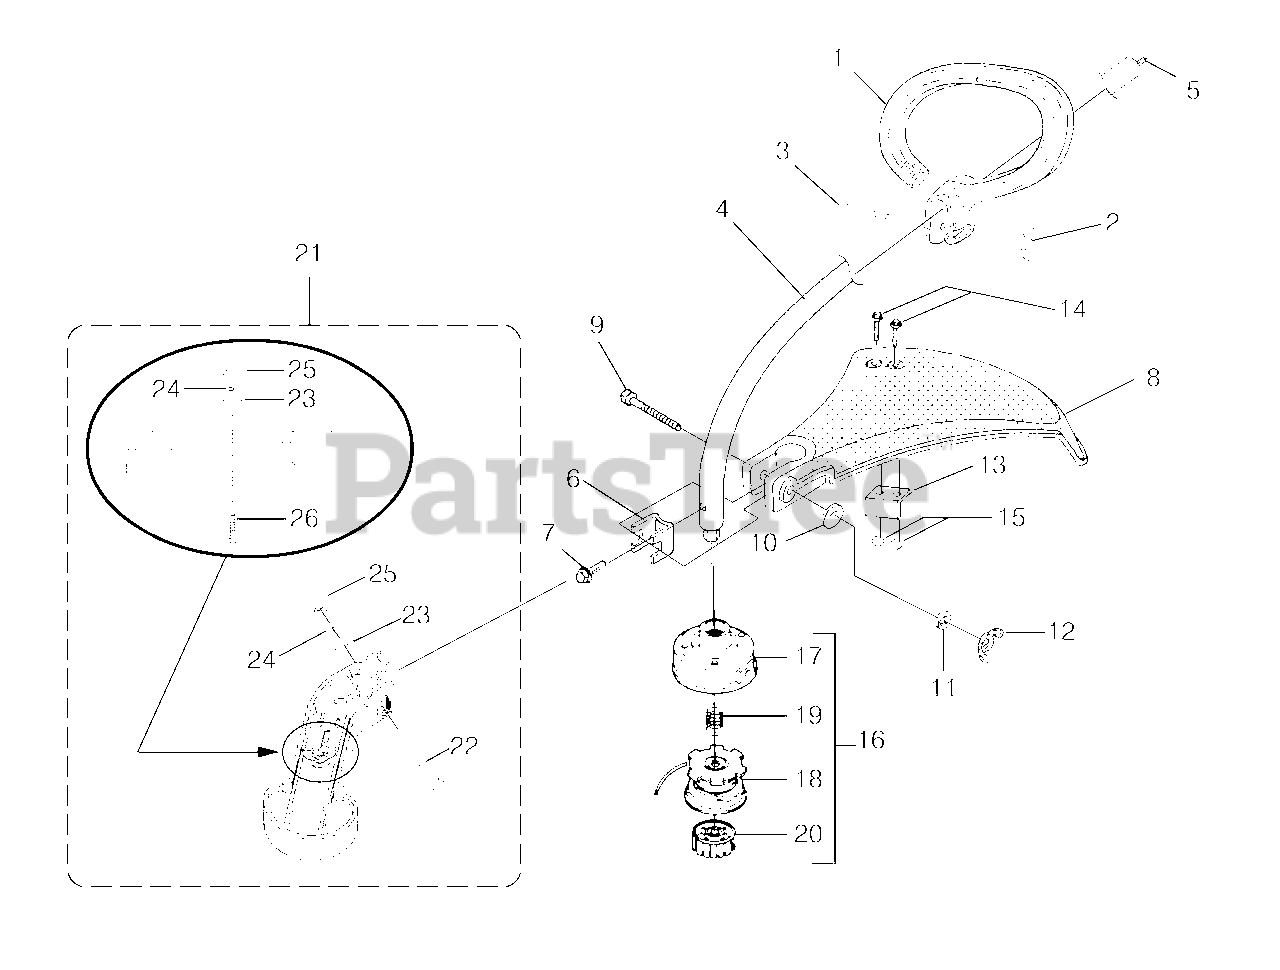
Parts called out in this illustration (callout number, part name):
1	HANDLE-Anti-Vibe
2	NUT-Wing, Washer Faced (1/4-20)
3	SCREW-Cap Hex Hd.
4	DRIVESHAFT ASSY.
5	SHAFT-Flexible
6	CLAMP
7	SCREW-Sems Hex Hd. (#10-24 X 3/8")
8	DEFLECTOR & BLADE KIT (55 Deg.)
9	SCREW-Cap Hex Hd. (10-24 X 2")
10	WASHER-Flat (1/4")
11	WASHER-Lock (1/4")
12	NUT-Wing, Washer Faced (1/4-20)
13	BLADE-Cut-Off
14	SCREW-Mech. Hex Hd. (10-24 X 7/8")
15	NUT-Hex (10-24)
16	STRINGHEAD-Complete (.080")
17	HOUSING & EYELET (Dual Line)
18	SPOOL & STRING (.080")
19	SPRING-Compression
20	RETAINER-Spool (R.H. Thread, Black)
21	EDGER GUIDE KIT
22	SCREW-Hex Hd. (1/4-20 X 2 1/2")
23	WASHER-Flat (1/4")
24	WASHER-Lock (1/4")
25	NUT-Wing, Washer Faced (1/4-20)
26	SCREW-Hex Hd. (1/4-20 X 1")
